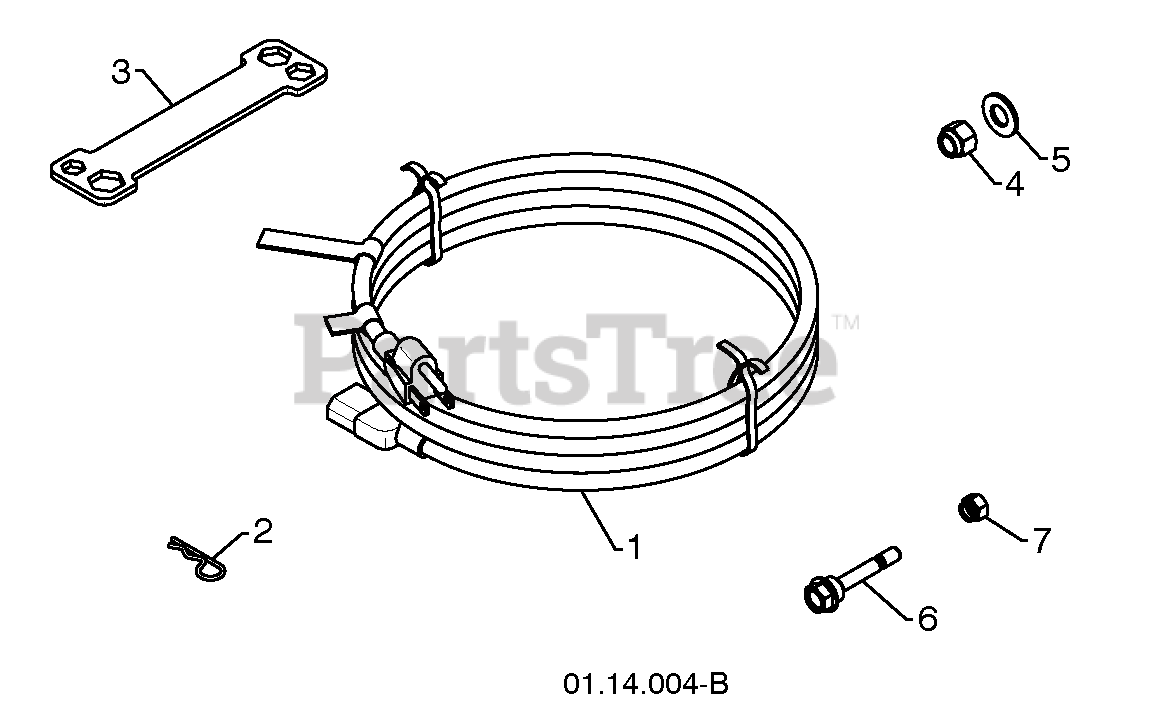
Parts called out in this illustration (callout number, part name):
1	POWER CORD
2	RETAINER PIN
4	LOCKNUT 3/8-16
5	WASHER 3/8
6	SHEAR BOLT 1/4-20 X 1-3/4
7	LOCKNUT 1/4-20
